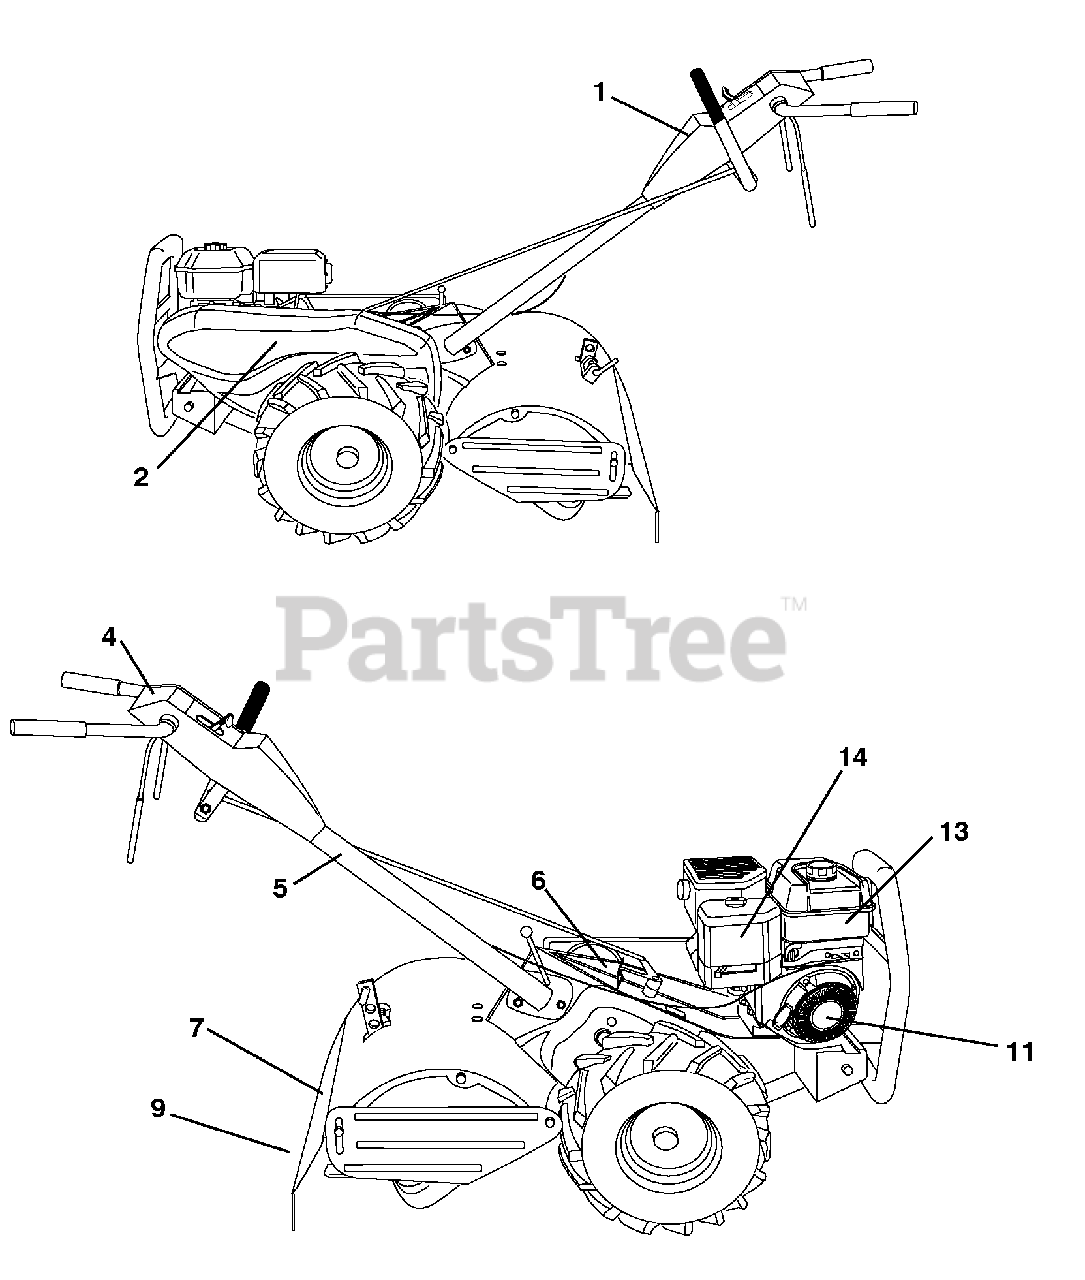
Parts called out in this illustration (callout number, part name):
1	Decal, CNTRL PNL
2	Decal, Decal, Blt Grd
4	Decal, Instruction, Tilling
5	Decal, Hand Placement
6	Decal, Shift Indicator
7	Decal, Caution
9	Decal, Warning, Rotating Tines
11	Decal, Rewind
13	Decal, B&S Tank
14	Decal, B&S, Air Cleaner
14	Manual, Operator's, English/French
14	Manual, Repair Parts, English/French
